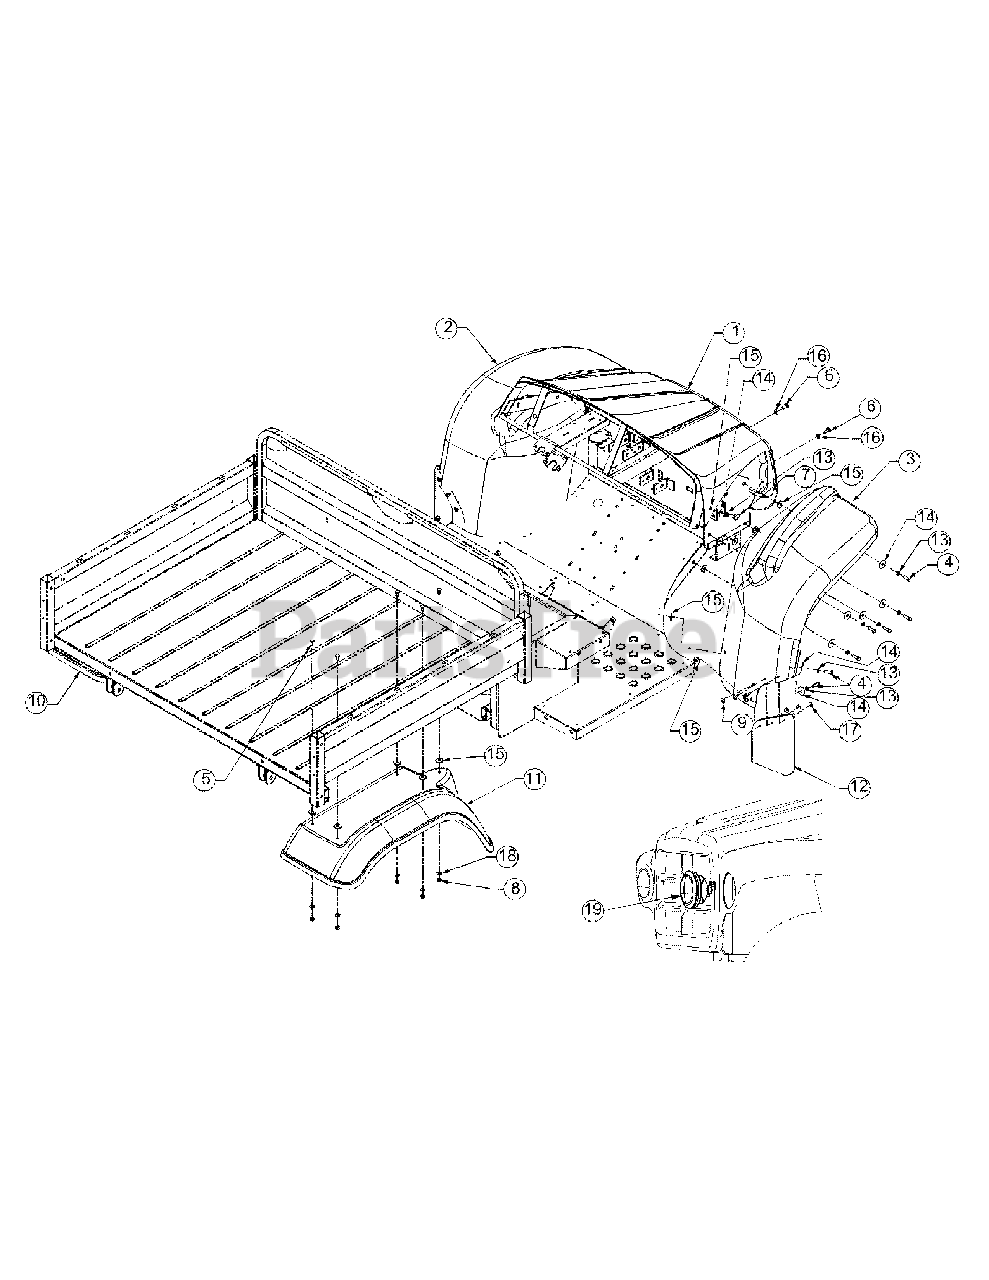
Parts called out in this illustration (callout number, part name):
1	Panel, Hood
2	Panel, Front Fender, LH
3	Panel, Front Fender, RH
4	Hex Screw, 5/16-18 x 1.0 Gr5
5	Hex Screw, 1/4-20 x .75
6	Hex Screw, 5/16-18 x .75 Gr5
7	Screw, Thumb 5/16-18
8	Hex Lock Nut, Nylon, 1/4-20
9	Rivet, Pop
10	Panel, Rear Fender, LH
11	Panel, Rear Fender, RH
13	Lock Washer, 5/16
14	Flat Washer, .350 x 1.25 x .06
15	Washer, Rubber, .310 x 1.0 x .125
16	Flat Washer, .44 x .688 x .65
17	Flat Washer, .194 x .62 x .063
18	Flat Washer, .271 x .630 x .065
19	Headlight Assembly
